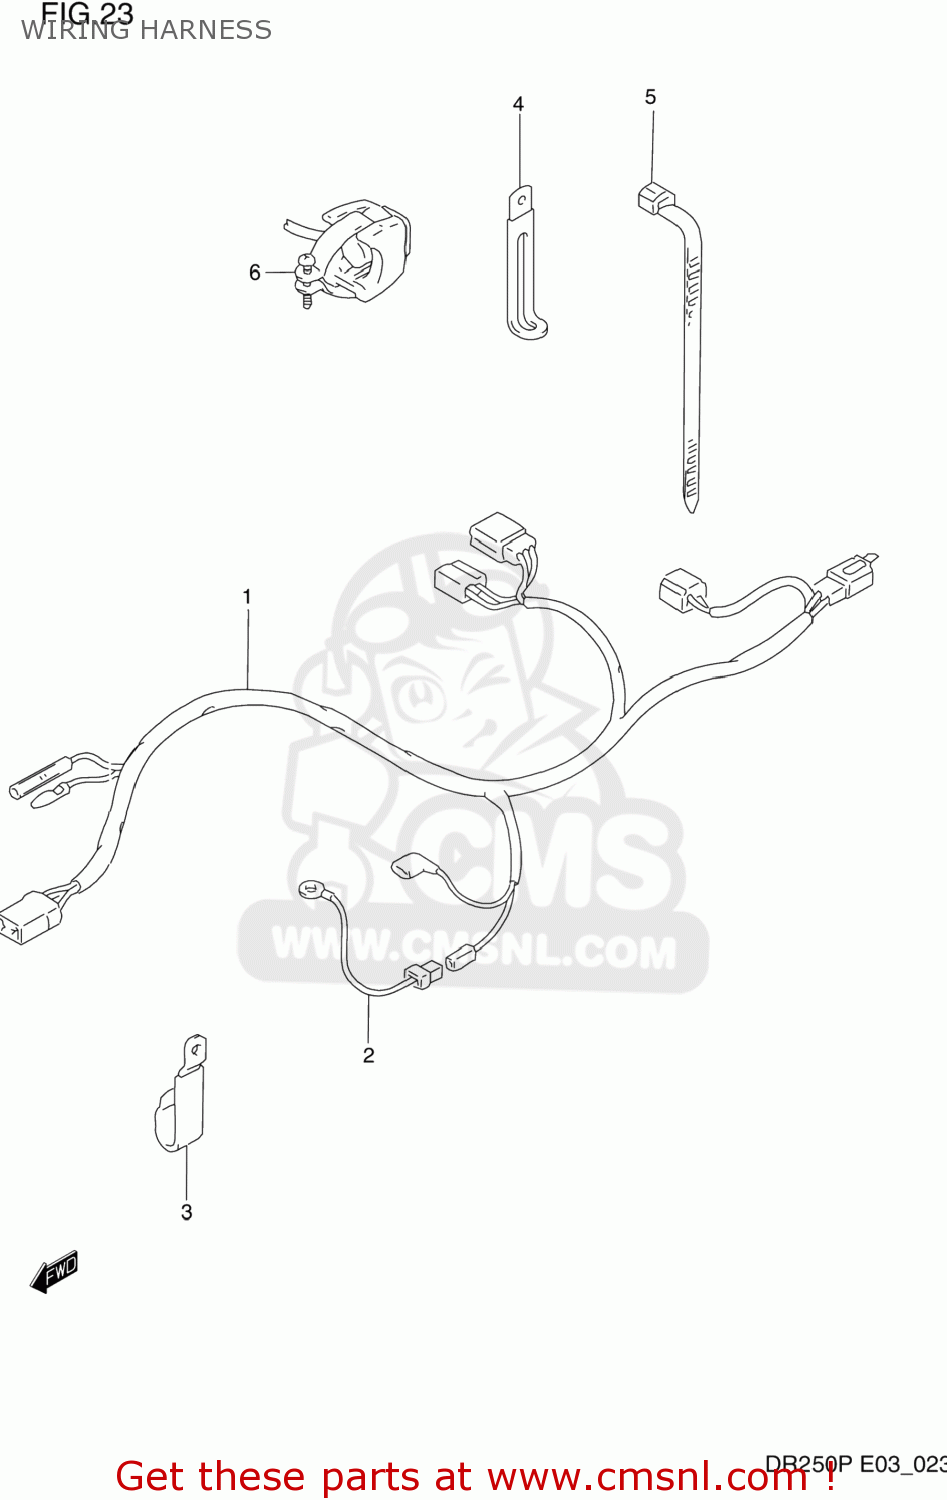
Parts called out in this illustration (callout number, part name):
1	HARNESS,WIRING
2	WIRE
3	CLAMP
4	CLAMP
5	CLAMP(L:125)
6	SWITCH ASSEMBLY
